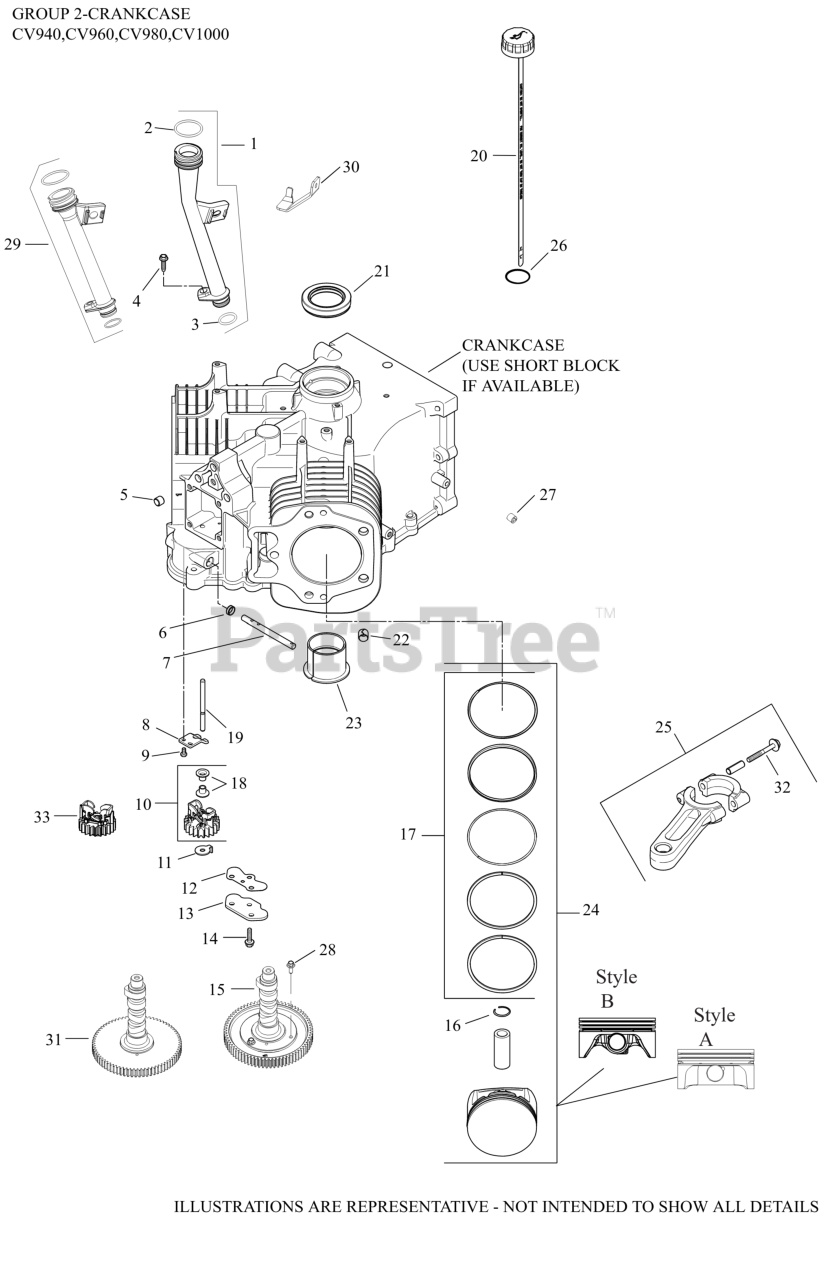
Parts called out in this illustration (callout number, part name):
1	KIT,OIL FILL TUBE
2	O-RING, UPPER OIL FILL TUBE
4	SCREW, THD FRM-USE 25 086 473-S
6	SEAL, GOVERNOR CROSS SHAFT
7	SHAFT, GOVERNOR CROSS
8	YOKE, GOVERNOR
9	SCREW, HEX HEAD
11	TAB, LOCKING
12	GASKET, LIFTER FEED COVER
13	KIT, COVER, LIFTER FEED
14	SCREW, HVY FLG M5X0.8X20
15	KIT, CAMSHAFT-USE 62 010 12-S
16	RETAINER, PISTON PIN
17	RING, SET PISTON (STD)
18	PIN, GOVERNOR REGULATING
19	SHAFT, GOVERNOR GEAR
20	DIPSTICK ASSEMBLY
22	PIN, LOCATING
24	KIT, PISTON ASSEMBLY (.25)
24	KIT, PISTON ASSEMBLY (.50)
24	KIT, PISTON (STD)
24	KIT, PISTON (0.25 OS)
24	KIT, PISTON (0.50 OS)
25	CONNECTING ROD ASSEMBLY
26	O-RING, DIPSTICK
27	PLUG, CTSK PIPE 1/8"
28	SCREW,HEX FLNGE
32	KIT, ROD BOLTS
33	KIT, GOVERNOR GEAR
